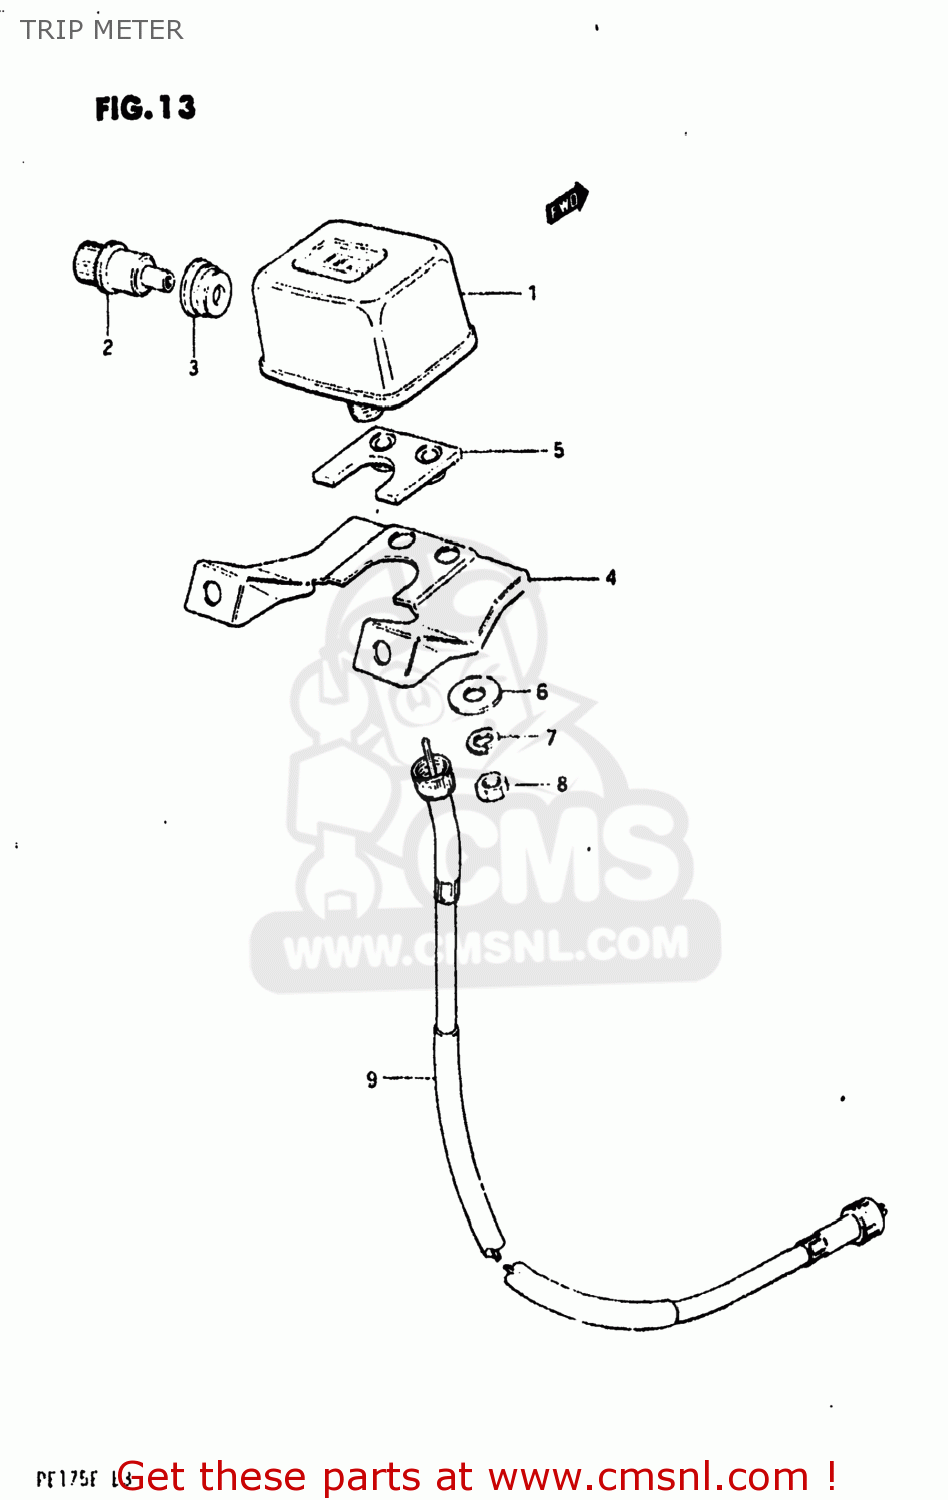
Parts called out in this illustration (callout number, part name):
1	TRIP METER
2	KNOB,TRIP METER
3	COVER,TRIPMETER KNOB
4	BRACKET,TRIPMETER
5	CUSHION,TRIPMETER
6	WASHER,METER
7	LOCK WASHER
8	NUT
9	CABLE ASSEMBLY,SPEEDOMETER
